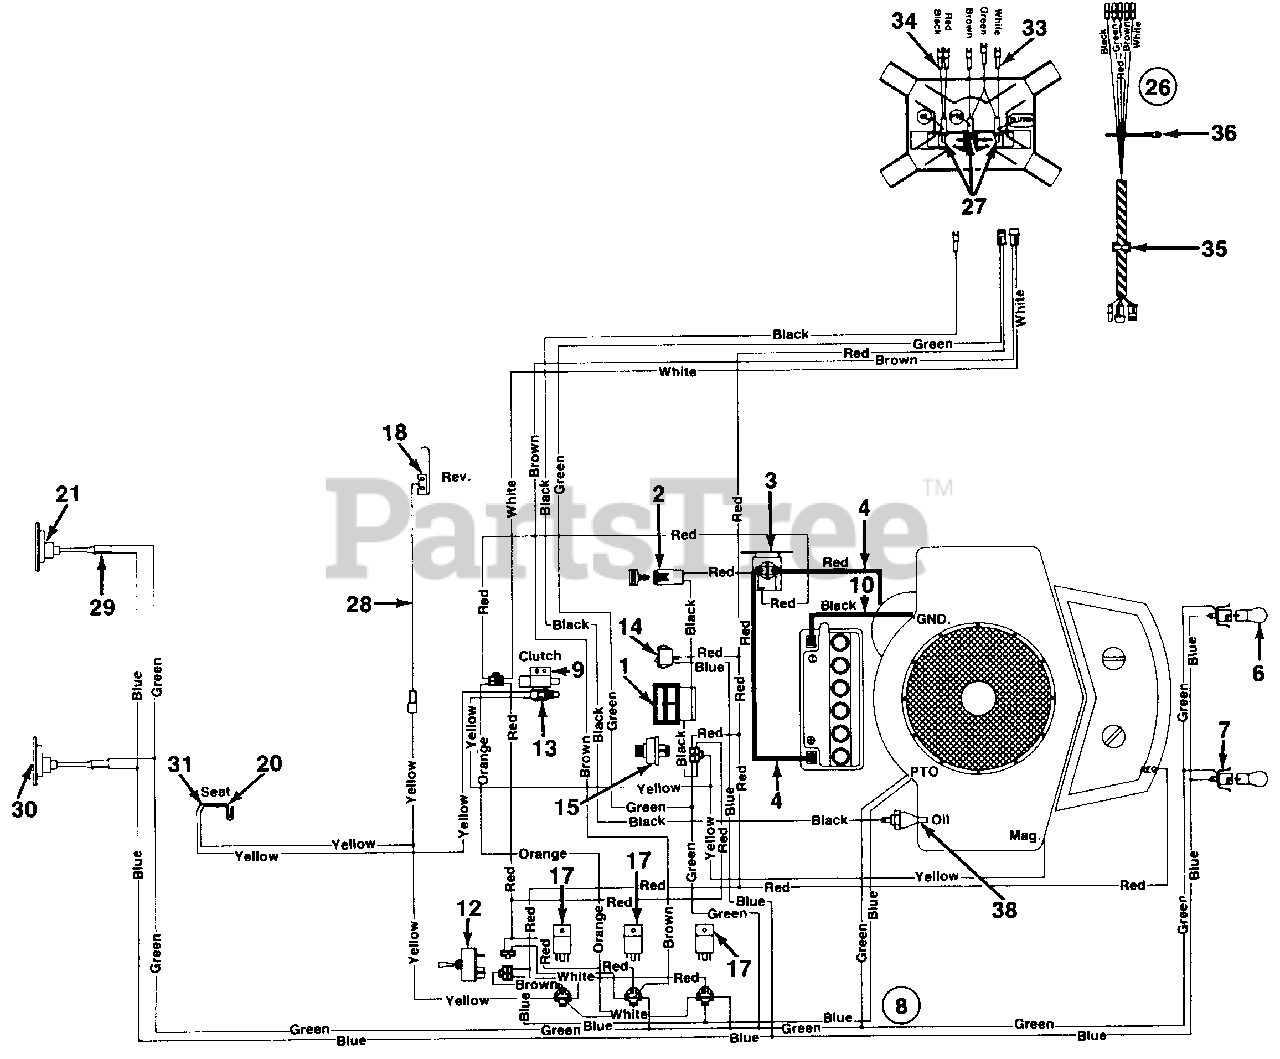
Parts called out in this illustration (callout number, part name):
1	Ammeter
2	Fuse 20 Amps
3	Solenoid
4	Wire
6	Bulb
7	Socket
8	Wire Harness
9	Safety Switch (Clutch)
10	6 Ga. Black Wire
12	Switch (PTO)
13	Safety Switch (Clutch)
14	Light Switch
15	Ignition Switch
17	Relay
18	Spring Lever
20	Safety Switch (Seat)
21	Taillight
26	Monitor Shaft Harness
27	Bulb
28	Transmission Ext. Wire
29	Taillight Harness
31	Safety Switch (Seat)
33	Monitor Light Harness Dual
34	Monitor Light Harness Single
35	Wire Clip
36	Cable Tie
38	Oil Pressure Switch
